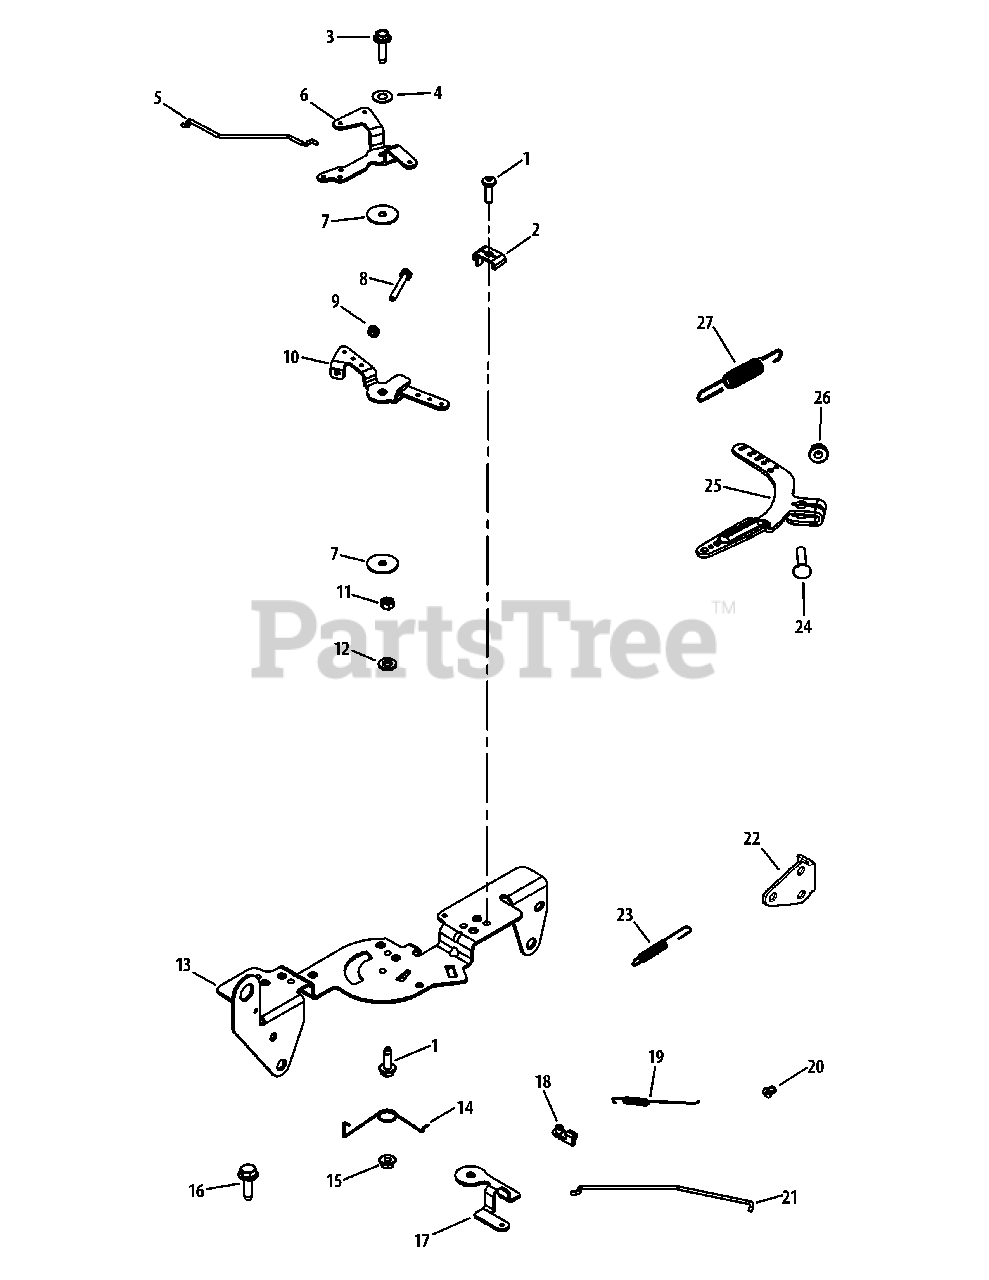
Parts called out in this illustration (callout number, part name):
1	Thread Forming Screw
2	Cable Clamp
3	Thread Forming Screw
4	Spring Washer, 1/4
5	Choke Linkage
7	Flat Washer, 5.5 MM
8	Cap Screw, M4 x .7 x 30
9	Nut, M4 x 0.7
10	Throttle Control Lever
11	Flange Nut, M5 x .8
12	Spring Lock Washer, 1/4
13	Control Bracket
14	Choke Return Spring
15	Lock Nut, M5 x .8
16	Thread Forming Screw
17	Throttle Actuator Lever
18	Throttle Linkage Bushing
19	Linkage Spring
20	Linkage Retaining Bushing
21	Throttle Linkage
23	Throttle Limiter Spring
24	Bolt, M6 x 1.0 x 25
25	Governor Lever
26	Flange Nut, M6 x 1.0
27	Governor Spring (Purple)
